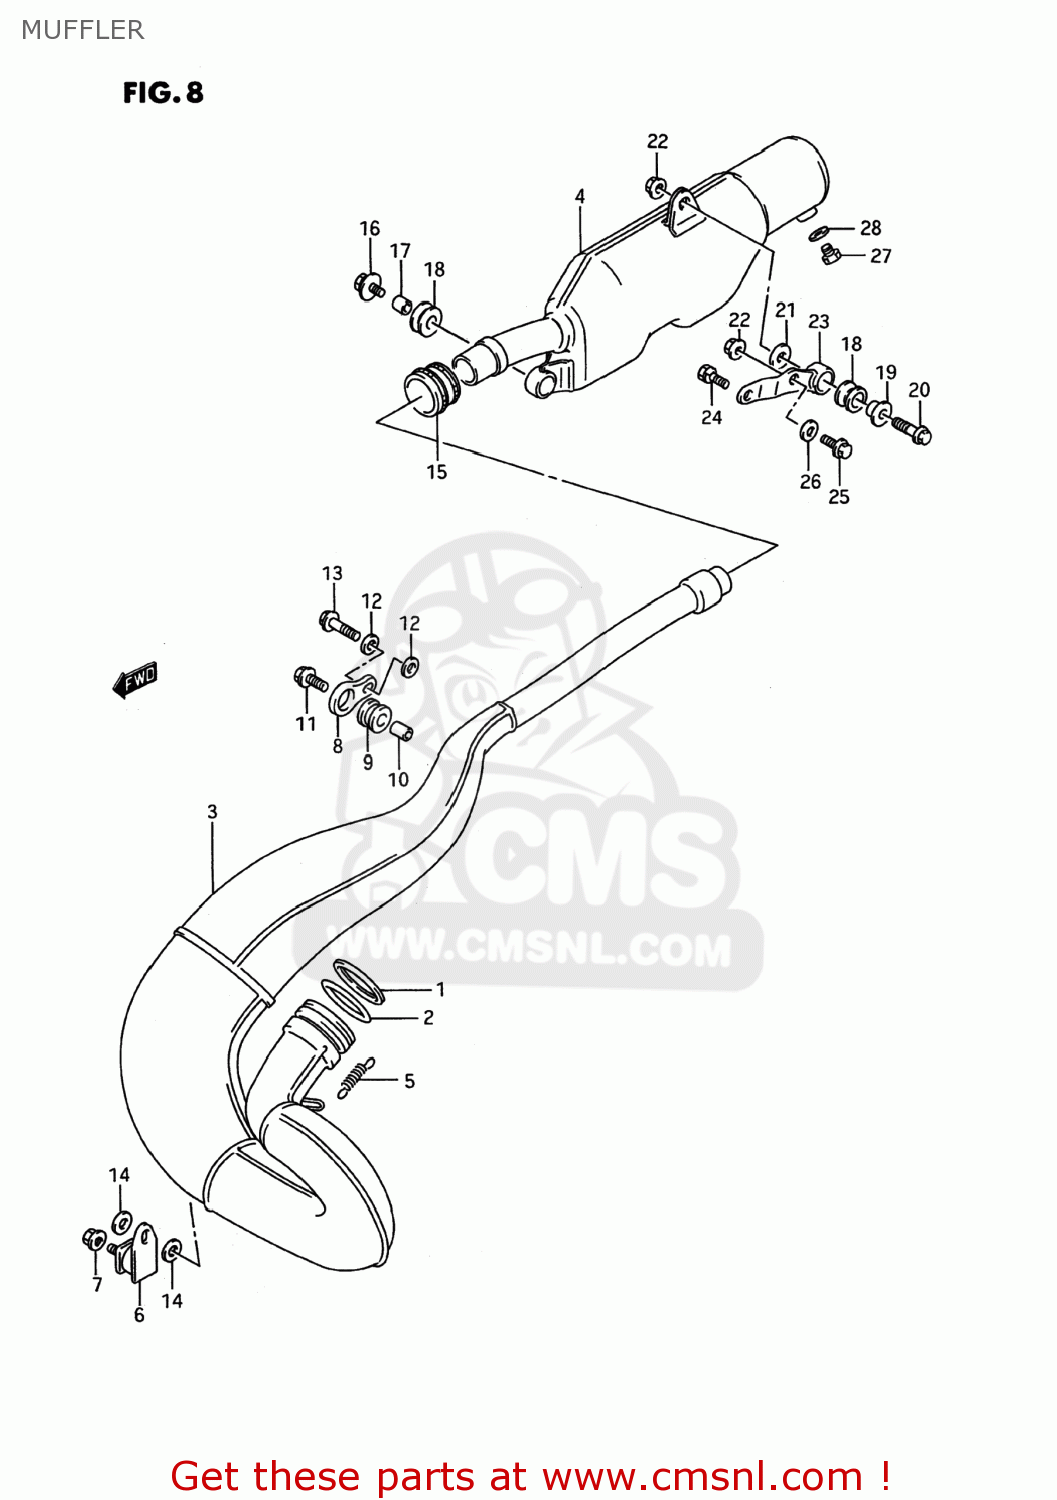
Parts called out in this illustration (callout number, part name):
1	WASHER,EXHAUST PIPE
2	O RING,EX PIPE
3	BODY,MUFFLER,FIRST
4	BODY,MUFFLER,SECOND
5	SPRING
6	DAMPER,MUFFLER SUPPORT
7	NUT
8	PLATE,MUFFLER MTG
9	CUSHION,MUFFLER
10	SPACER(6.4X9X16)
11	BOLT
12	WASHER (6.5X20X1.2)
13	BOLT
14	WASHER
15	CONNECTOR,MUFFLER
16	BOLT(8X35)
17	SPACER (8.6X12X17.5)
18	CUSHION
19	SPACER(8.6X12X17.5)
20	BOLT
21	WASHER (8.5X29X1.6)
22	NUT
23	BRACKET COMP,MUFFLER SUPPORT
24	BOLT
25	BOLT
26	WASHER(8.5X20X1.6)
27	PLUG(12X9)
28	GASKET(12.1X16.2X3.7) (NAS)
